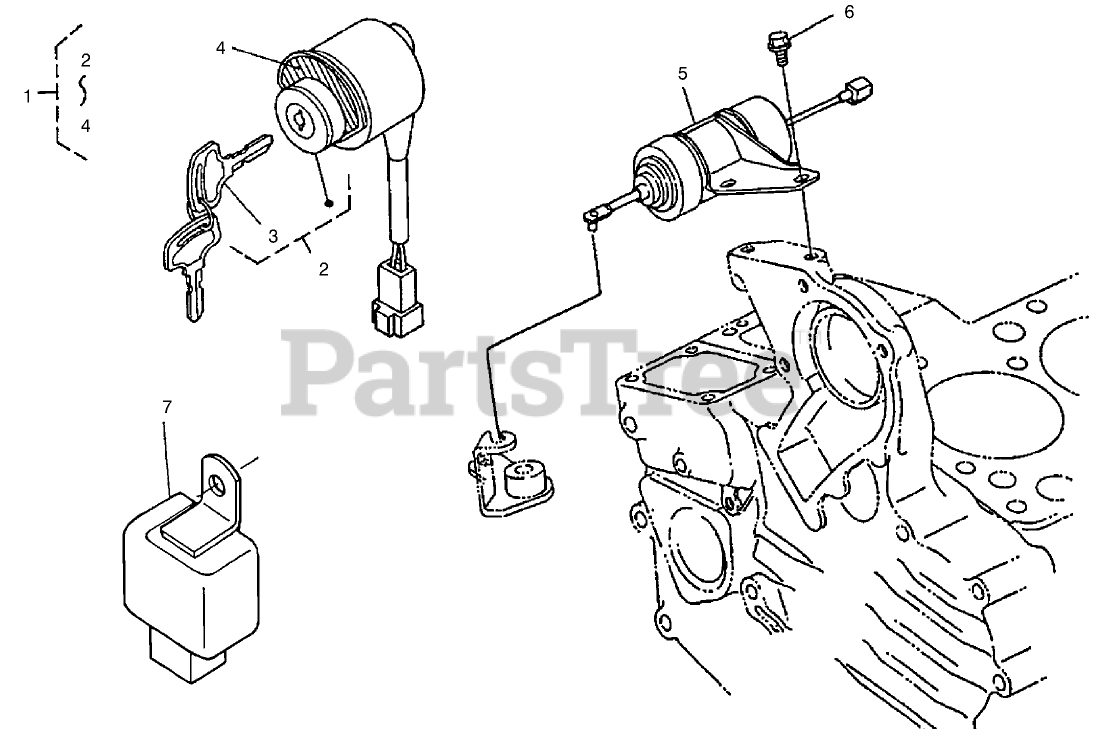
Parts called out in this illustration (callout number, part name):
1	ASSY SWITCH, STARTER
2	ASSY SWITCH, STARTER
3	KEY, STARTER
4	LABEL, STARTER SWITCH
5	SOLENOID, STOP
6	BOLT-FLANGE
7	Timer (S/N 534271)
7	TIMER (S/N 534272)
